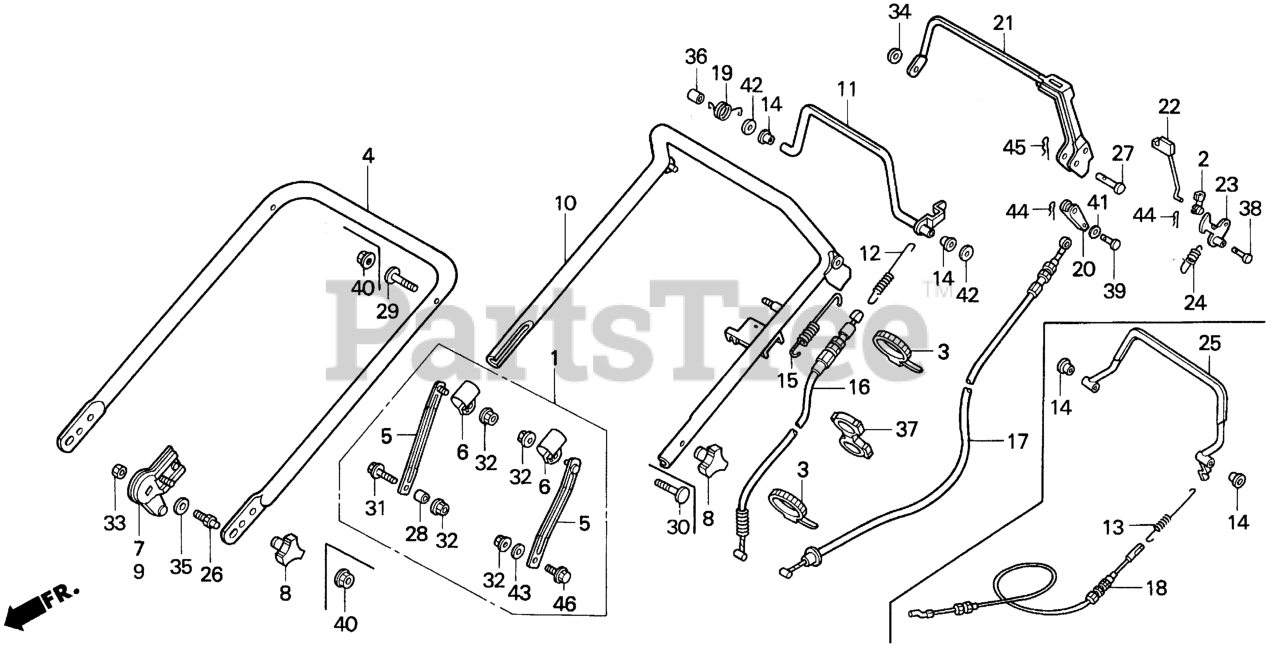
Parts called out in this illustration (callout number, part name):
1	SUPPORT KIT, HANDLE
2	JOINT, ROD
3	TIE, CABLE
4	PIPE, HANDLE (LOWER) (CHROME)
4	PIPE, HANDLE (LOWER) *NH105* (MAT BLACK)
5	PLATE, HANDLE SUPPORT
6	HANGER, HANDLE SUPPORT
7	STAY, R. HANDLE
8	GRIP, HANDLE JOINT (UPPER)
9	STAY, L. HANDLE *NH190M* (VINTAGE GRAY METALLIC)
10	PIPE, HANDLE (UPPER)
11	LEVER, CLUTCH
12	SPRING, CLUTCH
14	BUSH, CLUTCH LEVER
16	CABLE, SELF (CAPRO)
16	CABLE, SELF (NIPPON CABLE)
17	CABLE, ROTO-STOP (CAPRO)
19	SPRING, R. STOP RETURN
20	ARM, ROTO-STOP CABLE
21	LEVER, ROTO-STOP
22	ROD, RATCHET PUSH
23	LEVER, LOCK
24	SPRING, RATCHET RETURN
26	BOLT, HANDLE HOOK
27	PIN, CLUTCH LEVER
28	COLLAR, HANDLE SUPPORT
29	BOLT, HANDLE HOLDER (8X41)
29	BOLT (8X41)
31	BOLT, FLANGE (8X37)
32	NUT, SELF-LOCK (8MM)
33	NUT, SELF-LOCK (8MM)
35	WASHER, SPECIAL (22X8.5X2)
36	COLLAR (8X11X13.5)
37	CLIP, CABLE (22.2)
38	PIN, LOCK LEVER HINGE (6X30)
39	PIN, CABLE JOINT (6X17)
41	WASHER, PLAIN (6MM)
42	WASHER, PLAIN (8MM)
43	WASHER, PLAIN (8MM)
44	PIN, LOCK (6MM)
45	PIN, LOCK (8MM)
46	BOLT, FLANGE (8X16) Use from Engine SN 1000016.
